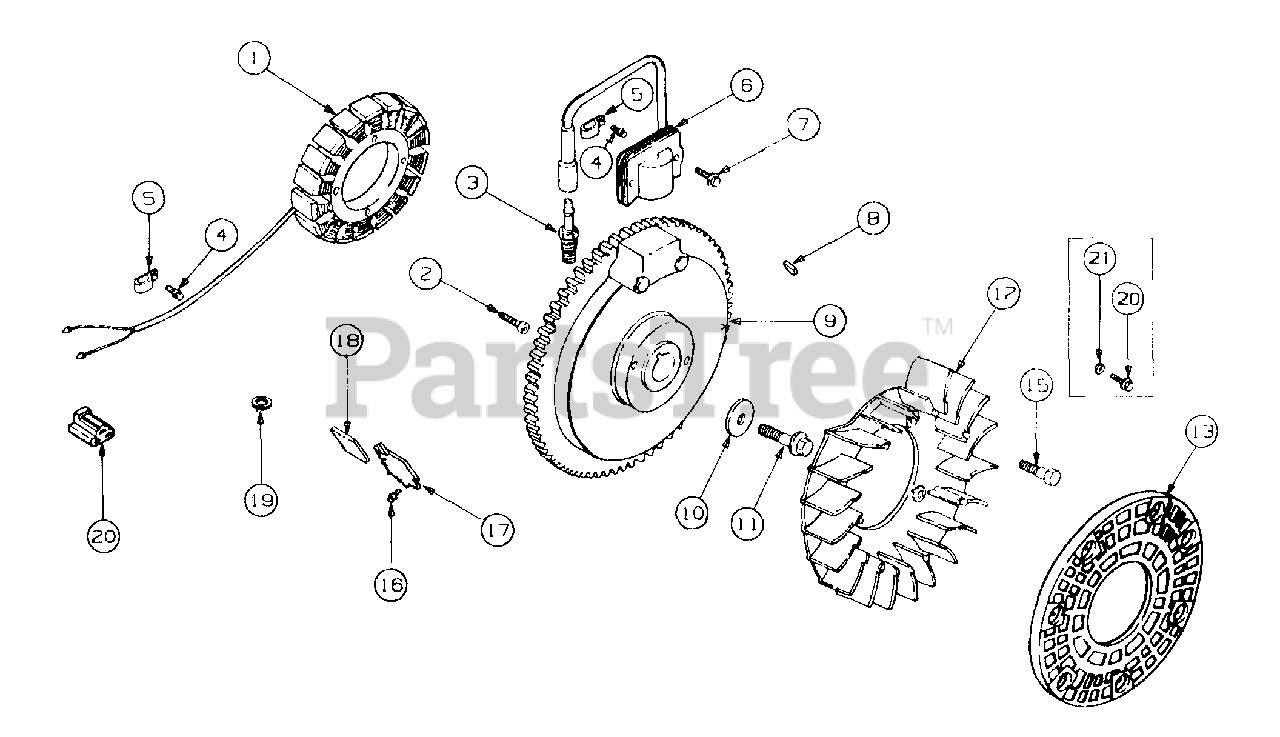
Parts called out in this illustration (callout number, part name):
1	Kit, Stator
2	Screw Stator Mntg M5 x 0.8 x 25
3	Spark Plug
4	Screw, Stator Harness Clip, M5 x .8 x 10
5	Clip, Cable
6	Module, Ignition
7	Screw, Ignition Module, M5 x .8 x 20
9	Flywheel Assy
10	Washer, Flywheel
11	Screw, Flywheel, M10 x 1.5 x 46
12	Fan
13	Screen, Grass
15	Bolt Shoulder M6 x 1 x 16
16	Screw, Rectifier, M6 x 1.0 x 16
17	Rectifier-Regulater
18	Connector, 3 contact
19	Washer, Lock, 1/4
20	Connector, 3 contact
21	Spacer
